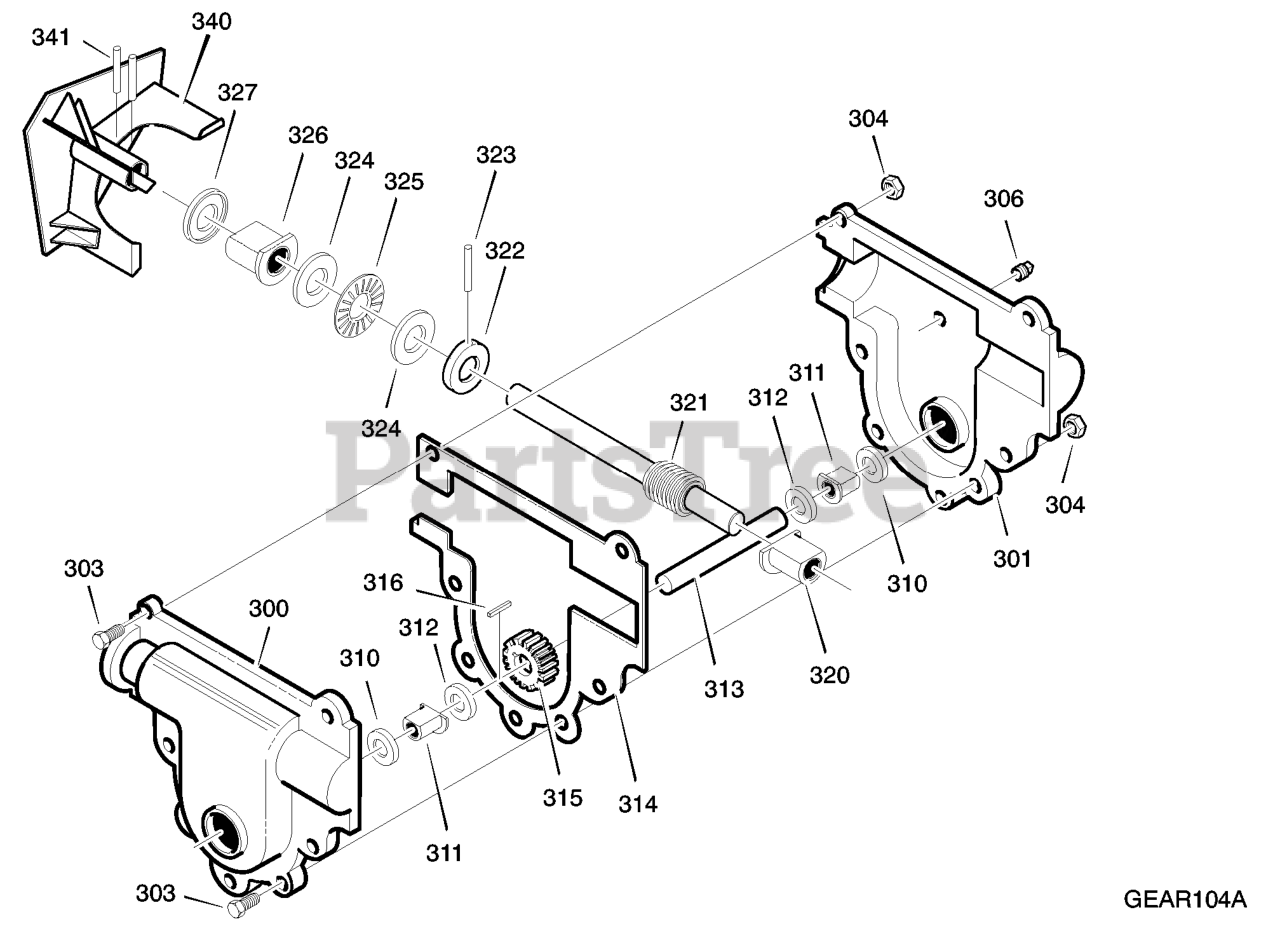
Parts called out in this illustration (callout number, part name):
300	CASE, GEAR, RH
301	CASE, GEAR, LH
306	SCREW
310	SEAL, OIL
311	BEARING, FL
312	WASHER, FLAT
313	SHAFT, OUTPUT
315	GEAR, WORM
316	KEY, WOODRUFF
320	BRNG, FL
321	SHAFT, INPUT
322	COLLAR, THRUST
323	PIN, SPRING
324	WASHER, FLAT
325	BRNG, ROLL
326	BRNG, FL
327	SEAL, OIL
340	IMPELLER ASSEMBLY
341	PIN, SPRING
